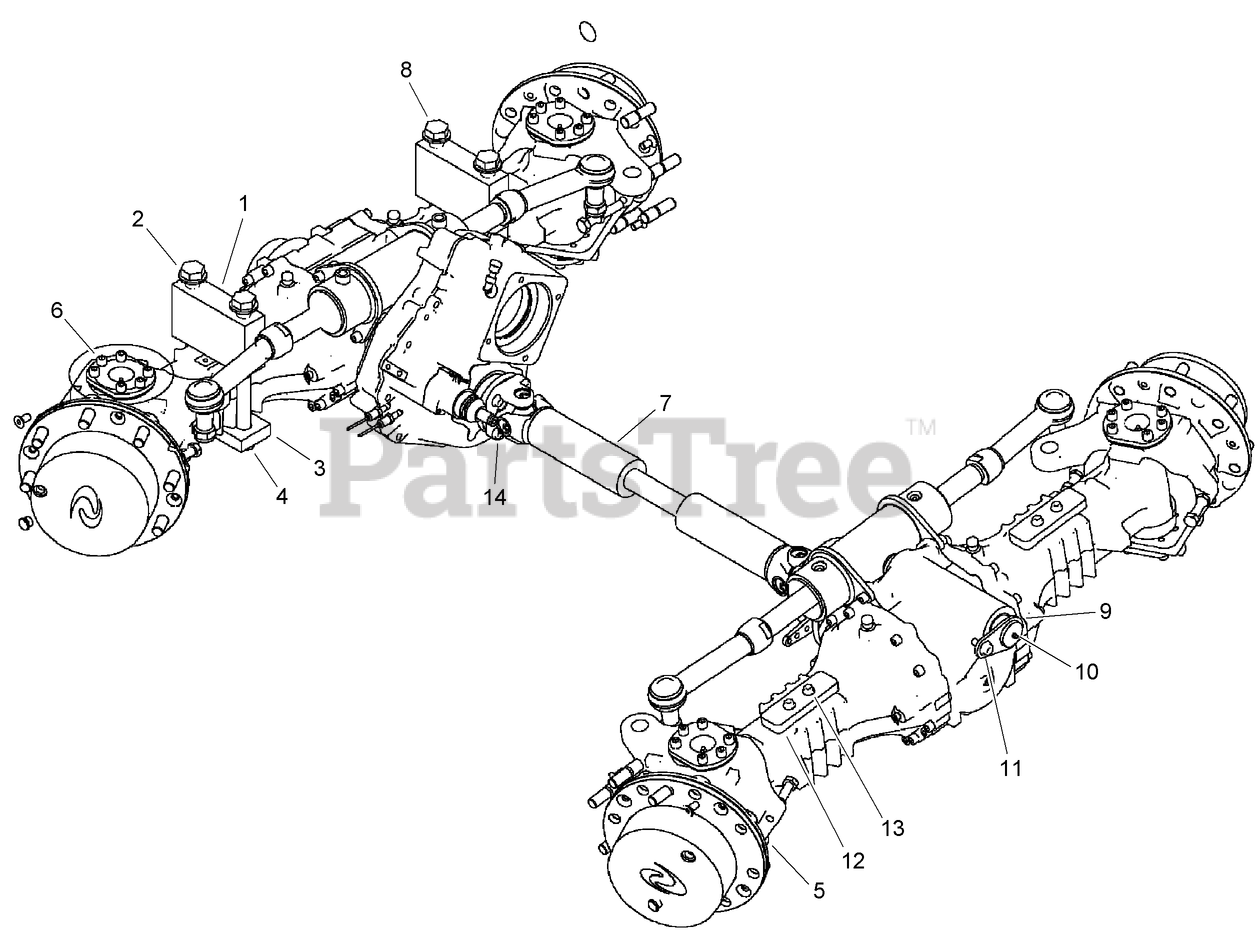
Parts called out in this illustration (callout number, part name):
1	SPACER-Axle Mounting
3	BAR-Clamp, Rear Axle Mtg
4	BOLT-Hex Hd 1 x 8 GR5 ZND
5	ASM-Axle, Front
6	AXLE-REAR
7	FRONT AXLE DRIVE SHAFT ASM
10	FITTING-Lube 1/4-28 Tpr SAE-LT .54 Long
11	SCREW, METRIC FLANGE w/BODY-M12 x 30
12	PLATE-Pivot Stop
13	SCREW-HHF
14	SCREW-FLANGE
